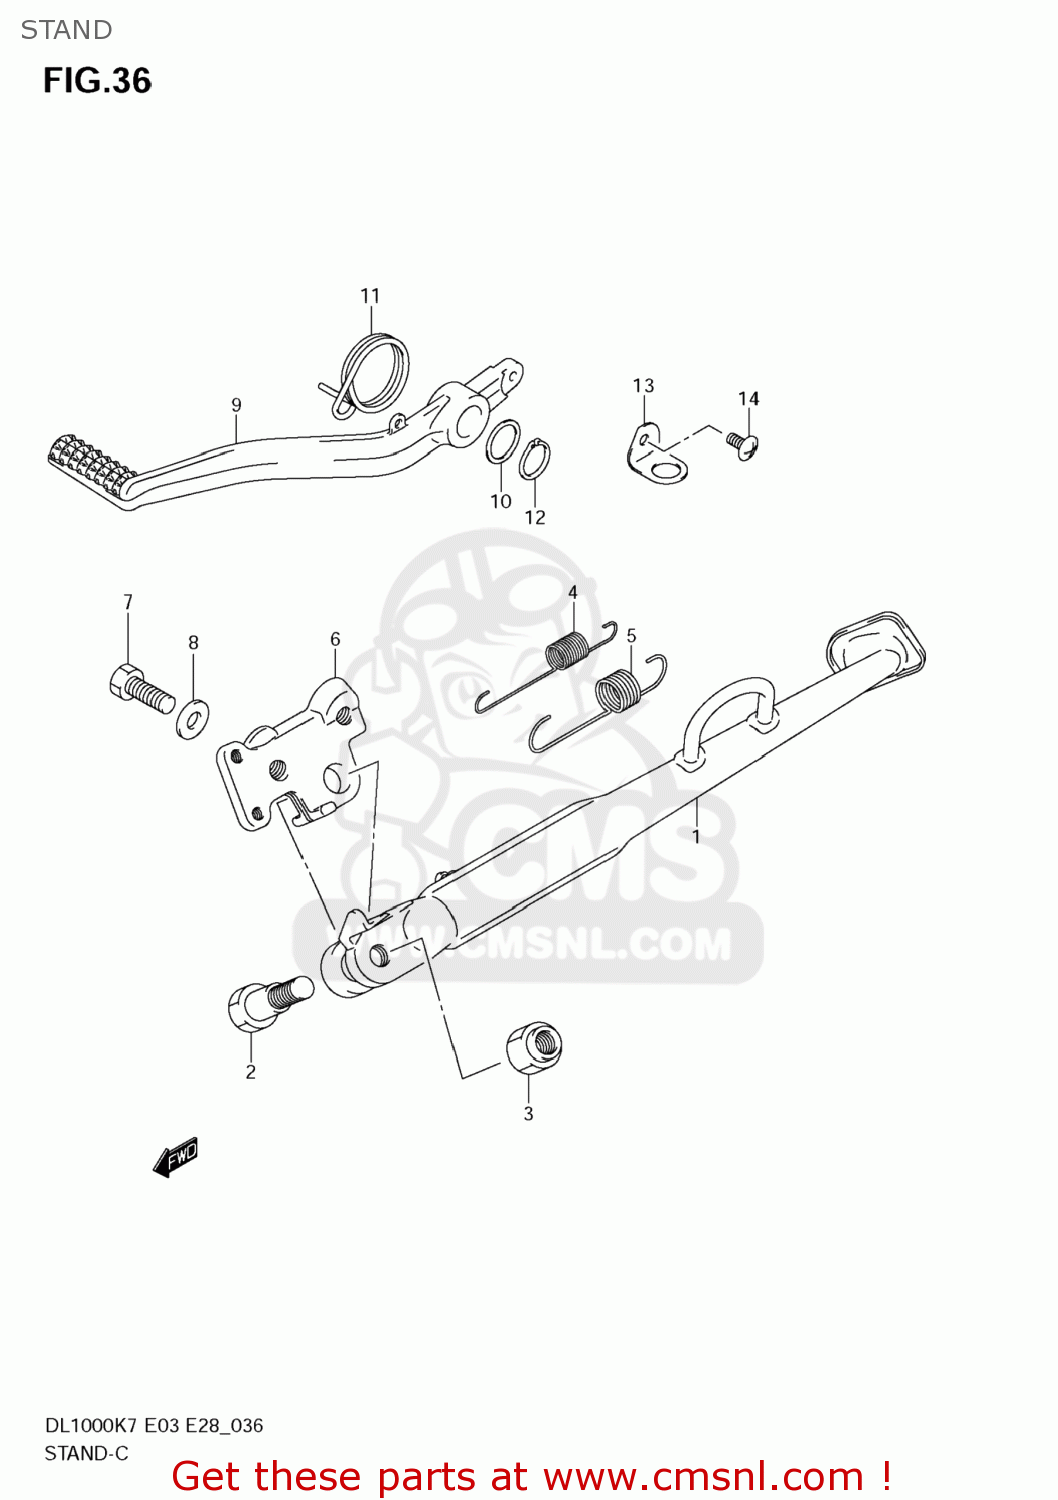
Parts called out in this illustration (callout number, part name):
1	STAND,PROP
2	BOLT(10X37.5)
3	NUT,PROP STAND
4	SPRING
5	SPRING
6	BRACKET, PROP STAND
7	BOLT(12X30)
8	WASHER(12.5X24X2.6)
9	PEDAL,BRAKE
10	WASHER(18X24X1)
11	SPRING
12	CIRCLIP
13	BRACKET,STOP LAMP SWITCH
14	SCREW
